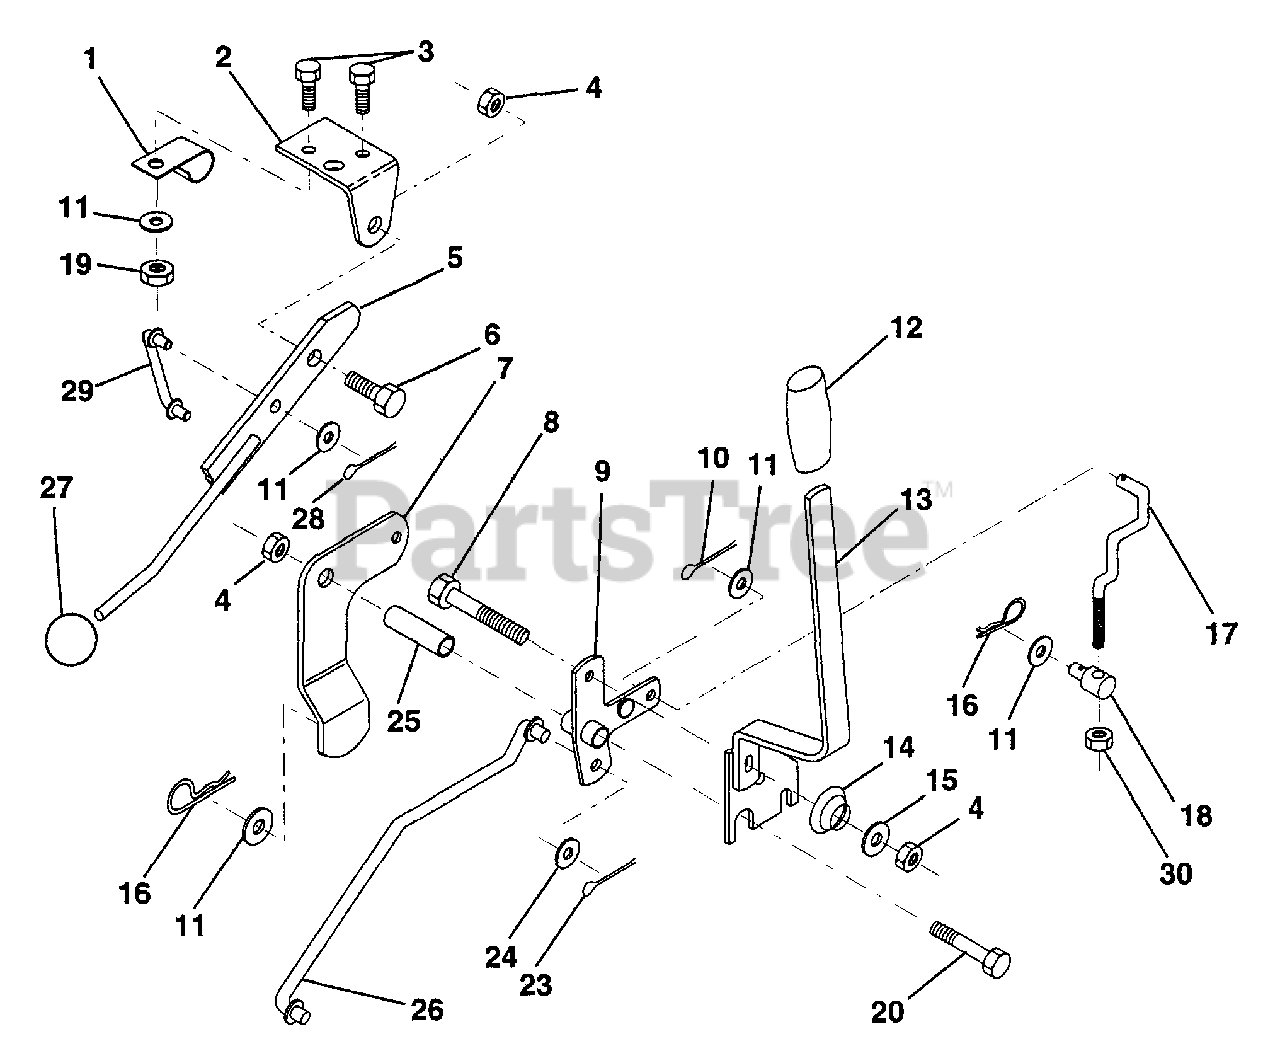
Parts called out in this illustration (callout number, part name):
1	Clip, Insulated
2	Bracket, Mower Clutch
3	Bolt, Hex Head, Fin. 1/4-20 UNC x 1/2 Grade 5
4	Nut, Crownlock 3/8-16 UNC
5	Clutch Lever Assembly
6	Bolt, Shoulder
7	Assembly, Mower Clutch Arm
8	Bolt, Hex 3/8-16 UNC x 2-1/4
9	Lift Bracket Assembly
10	Pin, Cotter 1/8 x 3/4
11	Washer 13/32 x 13/16 x 16 Ga.
12	Grip, Handle
13	Assembly, Lift Handle
14	Spring, Compression
15	Washer 13/32 x 3/4 x 12 Gauge
16	Retainer, Spring
17	Link, Front Lift
18	Trunnion, Threaded 3/8-16
19	Nut, Crownlock 1/4-20
20	Bolt, Hex Head, Fin. 3/8-16 UNC x 2-3/4
23	Pin, Cotter 1/8 x 1
24	Washer 17/32 x 1 x 16 Gauge
25	Tube, Spacer
26	Rod, Mower Lift
28	Pin, Cotter 3/32 x 3/4
29	Link, Mower Clutch
30	Nut, Centerlock 3/8-16 UNC
